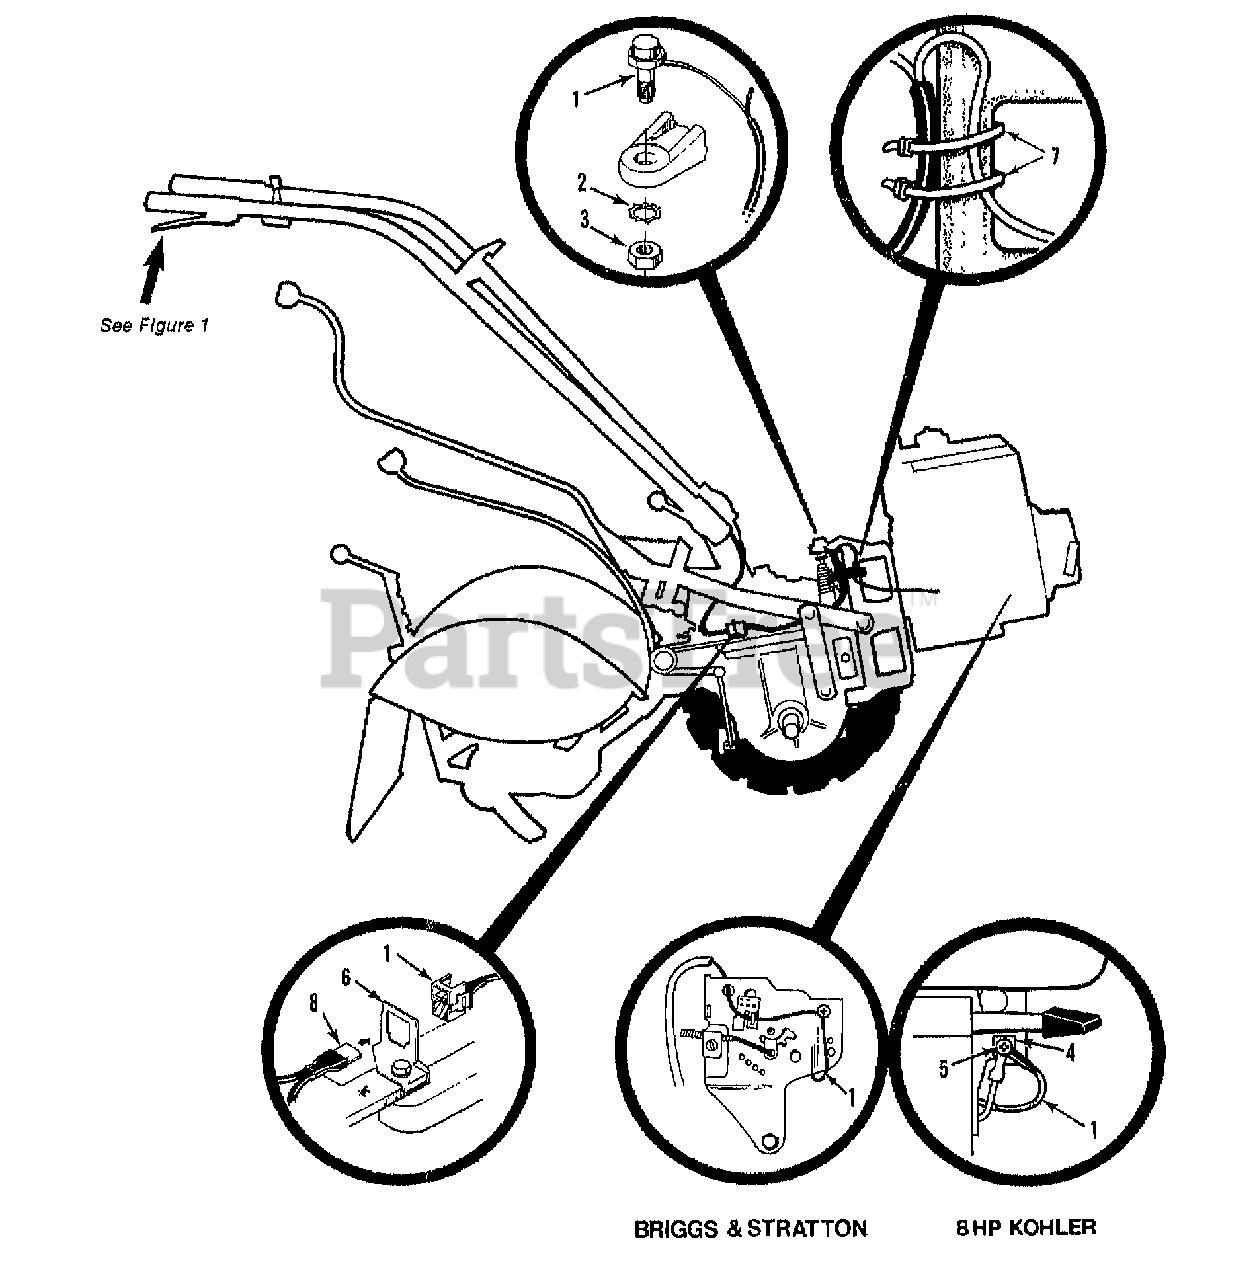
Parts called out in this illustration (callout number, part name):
1	HARNESS-WIRE ENG OPC PARTS NOT AVAILABLE SEPARATELY
2	WASHER-LK .438 EXT TOOTH
3	NUT-HEX/JAM 7/16-20
4	GROMMET-7 T/L & 8 KOH OPC
5	SCR #8-18 SELF TAP
6	CLIP-CONNECTOR
7	TIE-RED
8	HARNESS-WIRE OPC HORSE (ALSO SEE PAGE 2, REF. NO.20)
